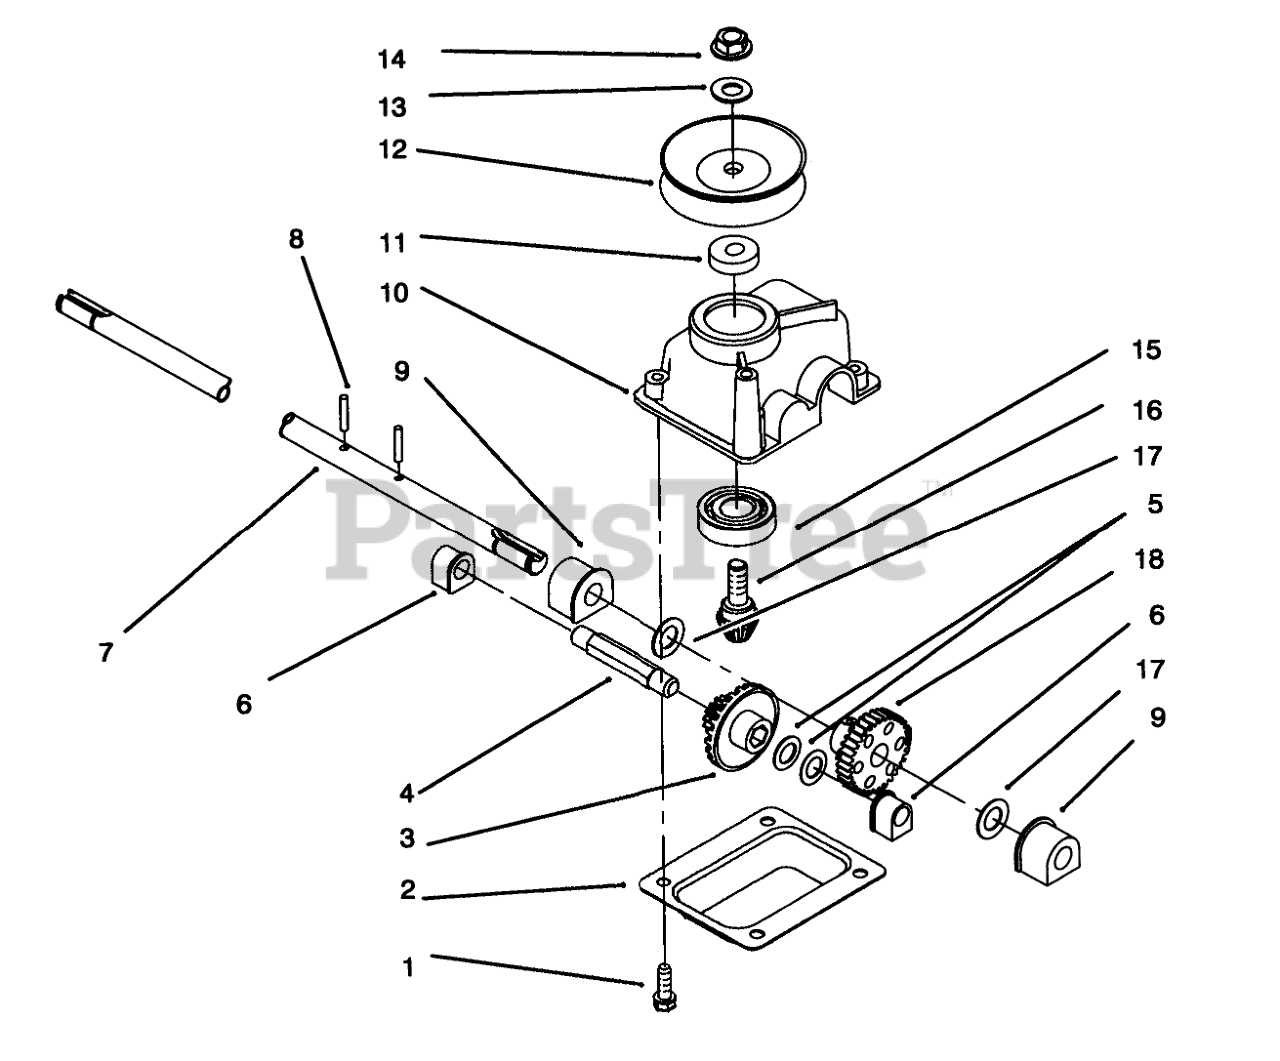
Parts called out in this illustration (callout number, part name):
1	SCREW-HWHTF
2	Cover-Gear Case
3	Gear-Bevel
4	SHAFT-INTERMEDIATE
5	WASHER-THRUST
6	BUSHING
7	Output Shaft
8	PIN-GROOVE
9	BUSHING
10	GEARCASE
11	SPACER
12	Pulley Half
13	WASHER-FLAT
14	NUT-HEX
15	BEARING-BALL
16	Gear-Pinion
17	WASHER-PLAIN
